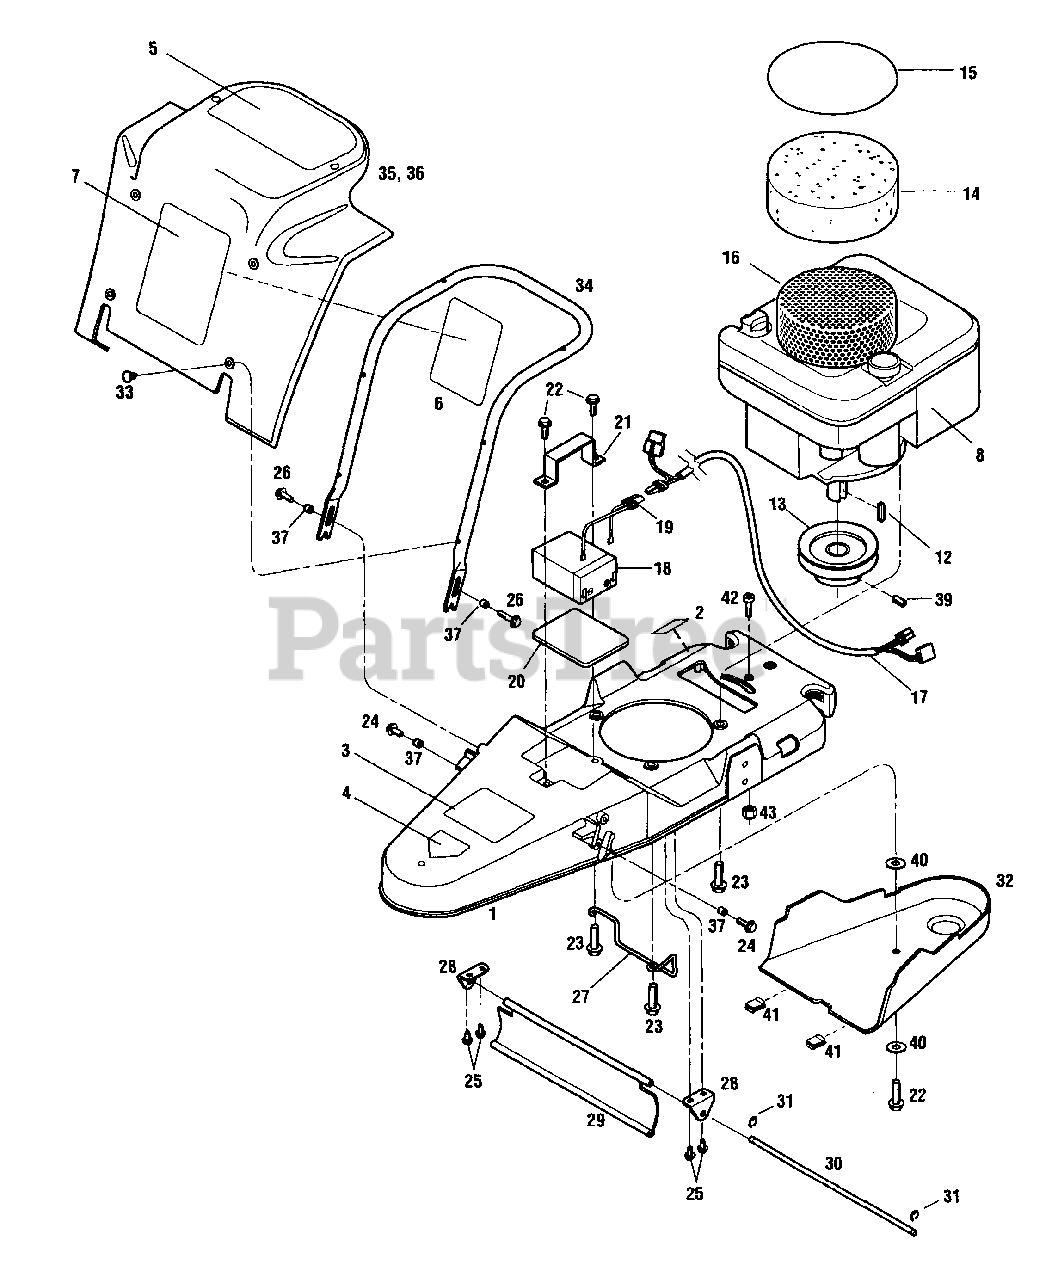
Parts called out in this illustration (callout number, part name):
1	Deck with decals
2	Decal-Hot Surface
3	Decal-Warning/Thrown Objects
4	Decal-Danger Feet/Hands
5	Decal-Engine Cover
6	Decal-Parallel Trim Control
7	Decal-Logo, 5HP
7	Decal-Logo, 4HP
12	Key, 3/16" x 1" Sq
13	Pulley, 4" OD
14	Engine Debris Guard/Foam
15	O-Ring/Engine Debris Guard
16	Engine Debris Guard
17	Wire Harness
18	Battery
19	Battery Connector
20	Battery Pad
21	Battery Bracket
22	Hex Hd. Flange Screw, 5/16-18 x 1
23	Hex Hd. Flange Screw, 3/8-16 x 1-1/2
24	Hex Hd Flange Screw, 1/4-20 x 3/4
25	Hex Hd Flange Screw, 1/4-20 x 5/8
26	Hex Hd Flange Screw, 1/4-20 x 1
27	Belt Guide
28	Flap Bracket
29	Deflector Shield
30	Deflector Shield Rod
31	E-Ring, 5/16"
32	Belt Cover
33	Push-in Fastener
34	Engine Cover Support
35	Engine Cover w/decals
36	Engine Cover w/decals
37	Spacer
39	Set Screw
40	Washer
42	Socket Hd Capscrew, 1/4-20 x 1
43	Toplock Nut, 1/4-20
